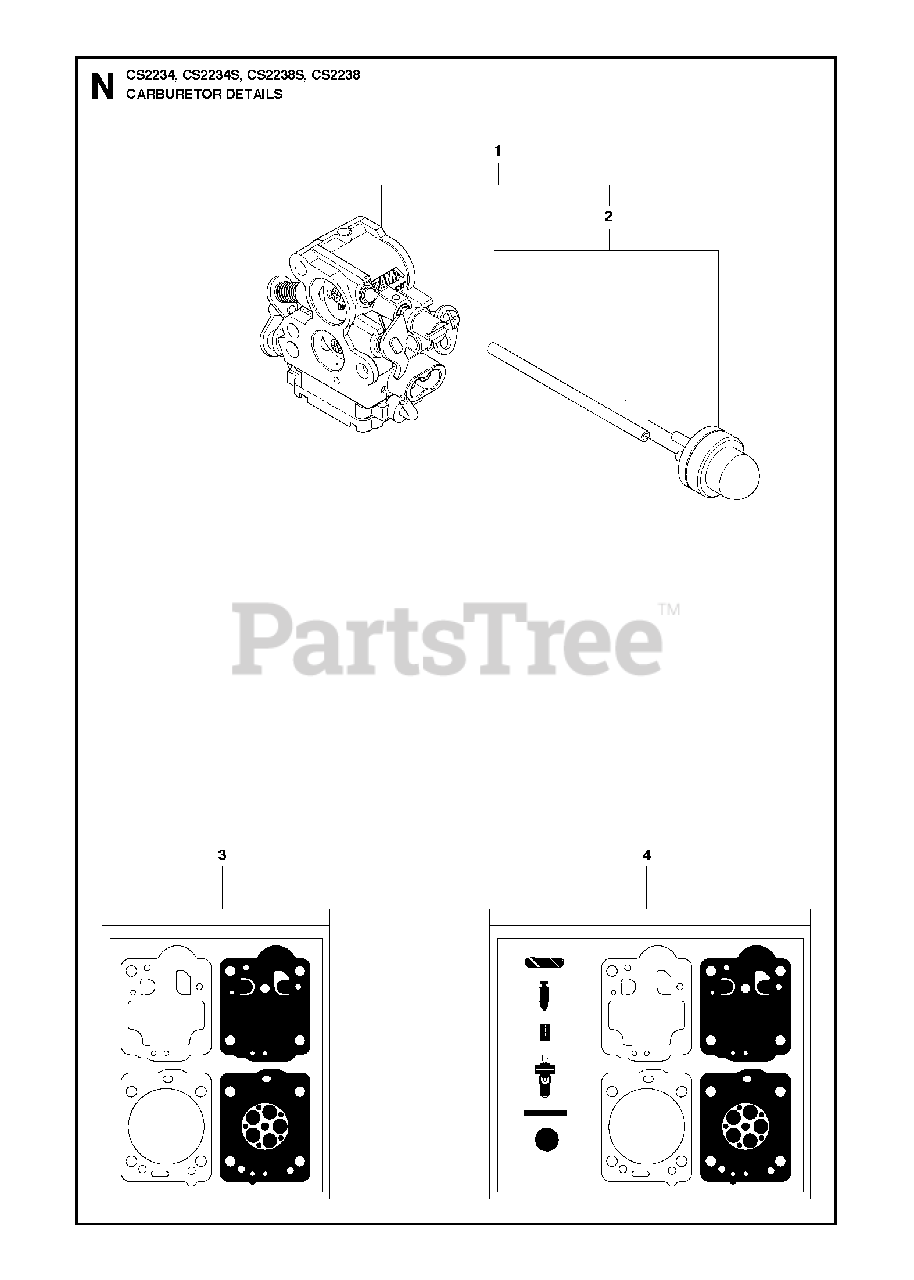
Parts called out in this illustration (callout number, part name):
1	CARBURETOR ZAMA ASSY
2	PURGE & LINE ASSY
3	KIT CARB GASKET
4	KIT CARB REPAIR
